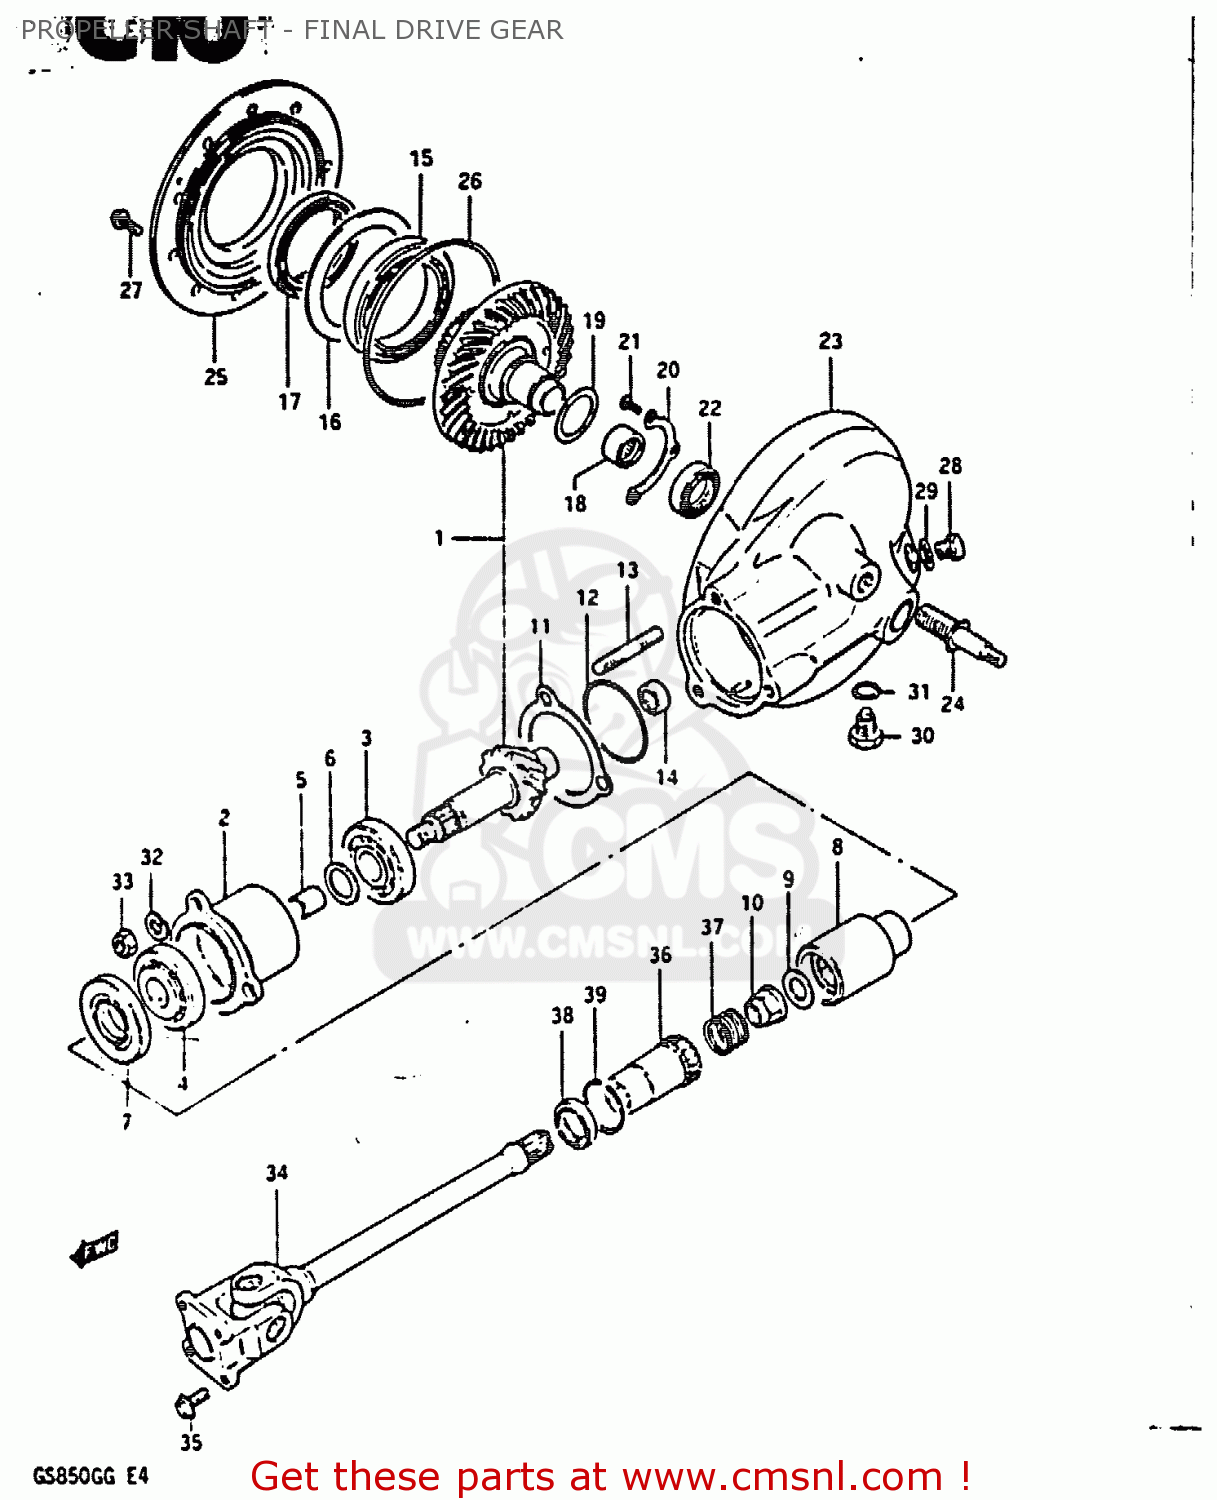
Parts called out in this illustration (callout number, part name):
1	GEAR SET,FINAL BEVEL
2	HOUSING,DRIVE GEAR
3	BEARING(25X52X19.25)
4	BEARING
5	SPACER (25.2X30X3.5)
6	SHIM (25X30X2
7	SEAL,OIL(32X54X7)
8	GEAR,FINAL DRIVE
9	WASHER(14X29X4)
10	NUT
11	SHIM,DRIVE GEAR HOUSING
12	O RING(D:2.4,ID:62.6)
13	STUD 10X30
14	BEARING(24X33X17)
15	BEARING(70X110X13)
16	SHIM,DRIVEN GEAR BEARING
17	SEAL,OIL(70X96X16)
18	BEARING(35X48X23.7)
19	SHIM,FINAL DRIVEN GEAR
20	RETAINER,FINAL DRIVEN GEAR BRG
21	SCREW 6X12
22	SEAL,OIL(30X42X7)
23	CASE ASSEMBLY,FINAL GEAR
24	STUD
25	CASE,FINAL GEAR BEARING
26	O-RING (D:3.1 ID:144.4)
27	BOLT
28	PLUG (14X12)
29	GASKET(14X19.2X2) (NAS)
30	PLUG
31	GASKET(14X19.2X2) (NAS)
32	LOCK WASHER
33	NUT
34	SHAFT ASSEMBLY,PROPELLER
35	BOLT(8X17)
36	COUPLING,PROPELLER SHAFT
37	SPRING
38	SEAL,OIL(30X40.5X5.5)
39	CIRCLIP
